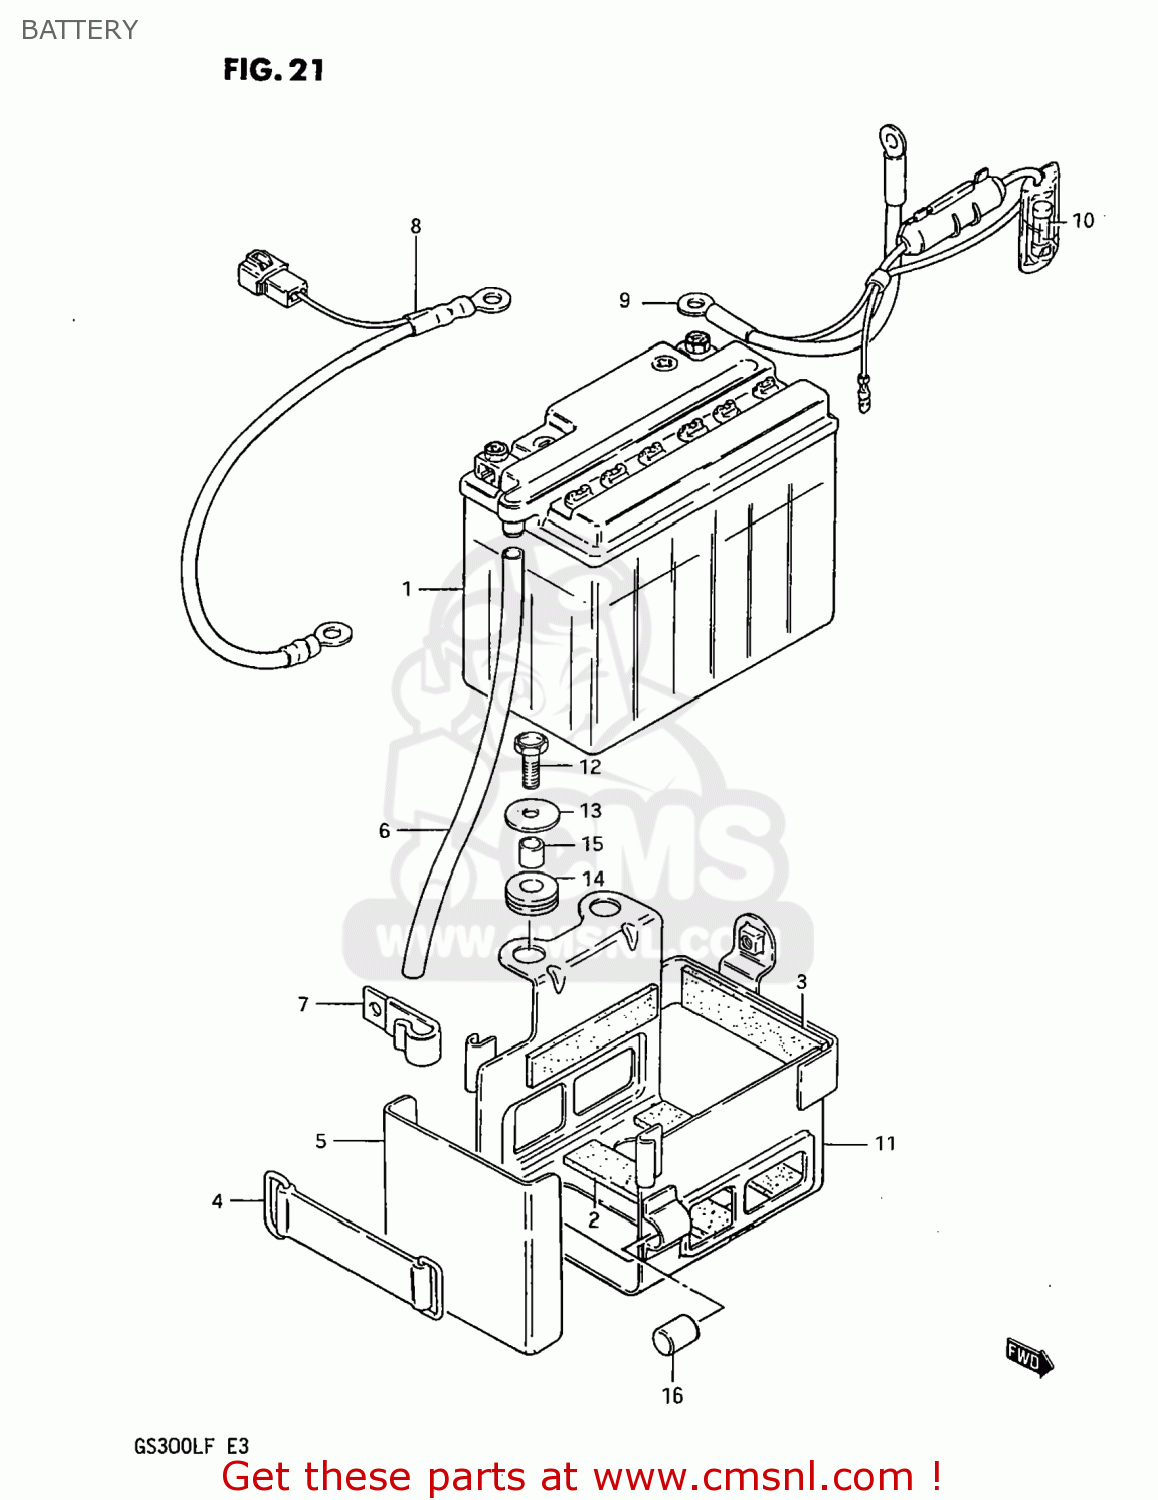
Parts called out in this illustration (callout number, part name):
1	BATTERY ASSEMBLY (12V)
2	PROTECTOR(170X95X3.0)
3	PROTECTOR,20X9
4	BAND
5	COVER,BATTERY
6	HOSE,BATTERY EXHAUST
7	CLAMP
8	WIRE,BATTERY MINUS
9	CASE ASSY,FUSE (WITH CABLE)
10	FUSE(15A)
11	HOLDER,BATTERY
12	BOLT,M6X1X20
13	WASHER
14	CUSHION
15	SPACER(6.1X9X7.5)
16	CUSHION
